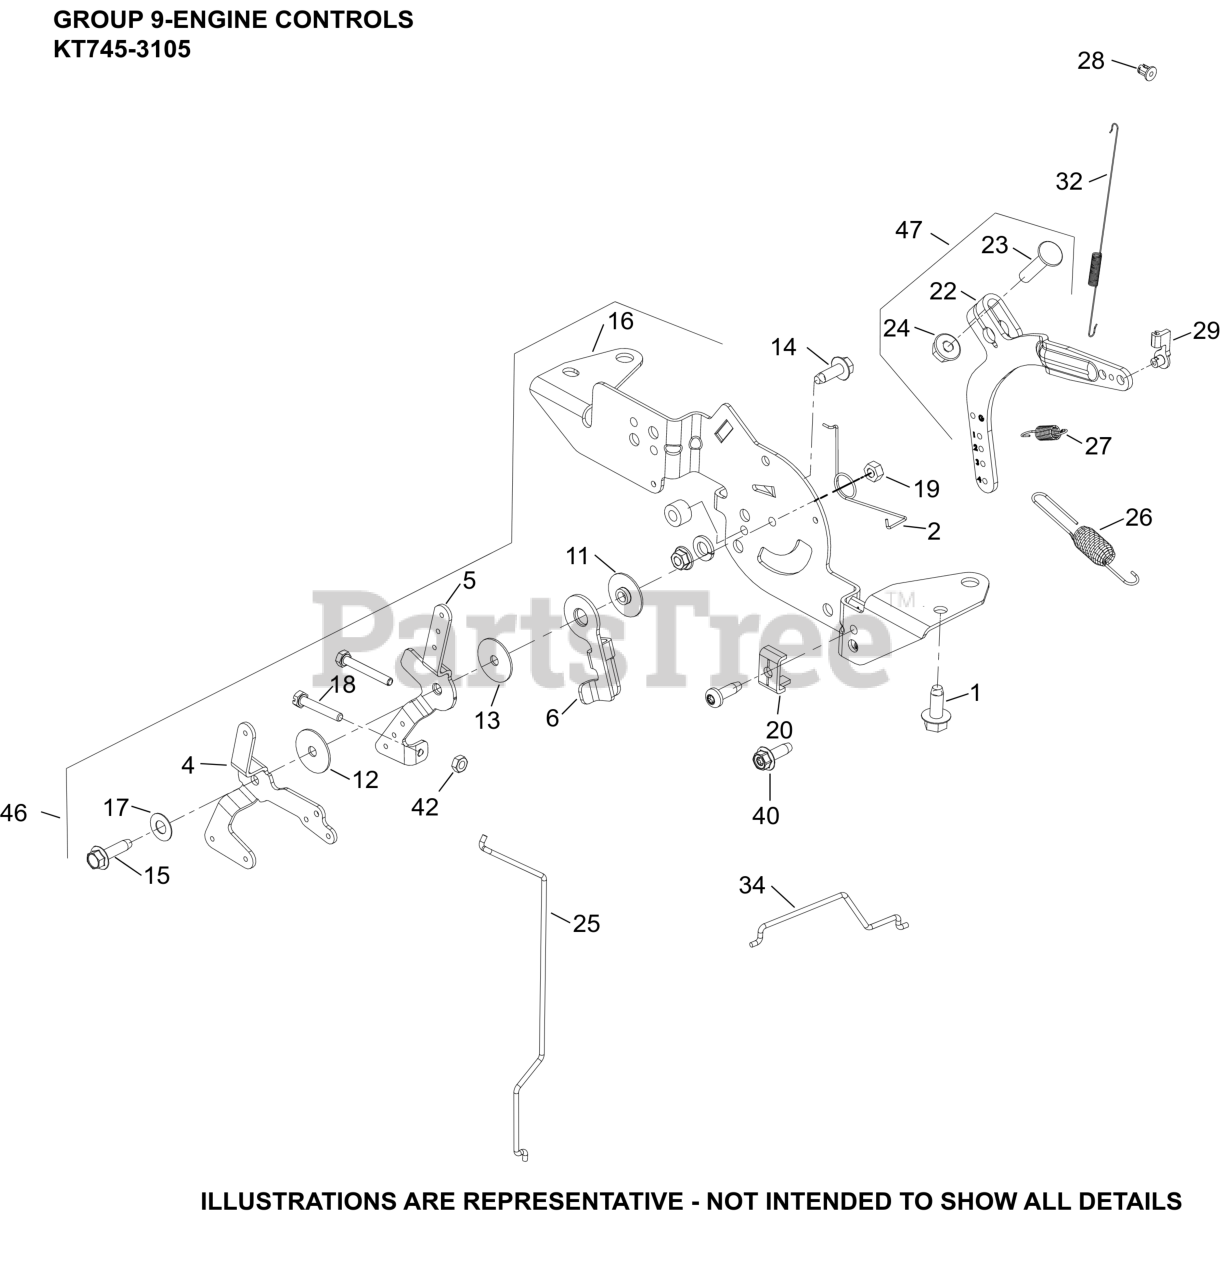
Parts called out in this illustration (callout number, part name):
1	SCREW, THREAD FORMING
2	SPRING, CHOKE RETURN
4	LEVER, CHOKE
5	LEVER, THROTTLE CONTROL
6	LEVER, THROTTLE ACTUATOR
11	SPACER, CONTROL ASSEMBLY
12	WASHER, FLAT 5.5 MM
13	WASHER, FLAT 5 MM
14	SCREW, THREAD FORMING
15	SCREW, THD FRM-USE 25 086 473-S
16	BRACKET, SPEED CONTROL
17	WASHER, SPRING 1/4"
18	SCREW, SLT HD CAP M4X0.7X25
19	NUT, LOCK M5X.8
20	CLAMP, CABLE CABLE
22	LEVER, GOVERNOR - (#2409069S)
23	BOLT, RD HD SQ NECK M6X1.0X25
24	NUT, FLG M6X1.0
25	LINKAGE, CHOKE
26	SPRING, GOVERNOR (ORANGE)
27	SPRING, GOVERNED IDLE
28	BUSHING, LINKAGE RETAINING
29	BUSHING, THROTTLE LINKAGE
32	SPRING, LINKAGE
34	LINKAGE, THROTTLE
40	SCREW, THREAD FORMING
42	NUT, M4X0.7
46	CONTROL ASSEMBLY, DUAL WIRE
47	LEVER, GOVERNOR ASSEMBLY
